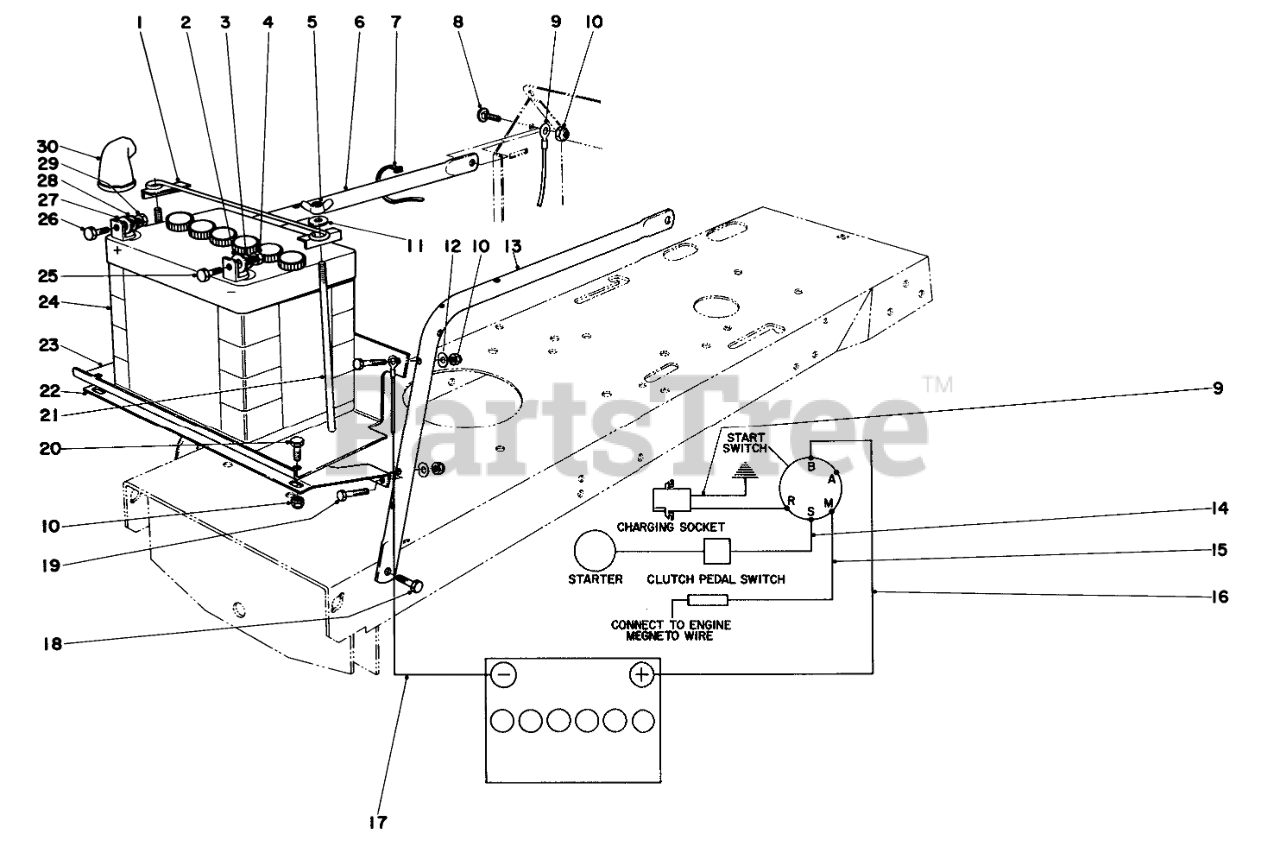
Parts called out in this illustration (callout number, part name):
1	Clamp
2	WASHER-FLAT
3	WASHER-LOCK
4	NUT-HEX
5	WING NUT
6	Support Gas Tank, Right
7	Cable Tie
8	SCREW-CARRIAGE
9	Wire Assembly
10	NUT-LOCK, CONE
11	WASHER-FLAT
12	WASHER
13	Support Gas Tank, Left
14	Wire-Starter Switch to Pedal Switch
15	Wire Assembly
17	Wire Assembly
18	SCREW-HH
19	SCREW-HH
20	SCREW-HH
21	BATTERY BOLT
22	Heat Shield
23	Battery Shelf
24	Battery
25	SCREW-HH
26	SCREW-HH
27	WASHER-FLAT
28	WASHER-LOCK/SP
29	NUT-HEX
30	BATTERY BOOT
